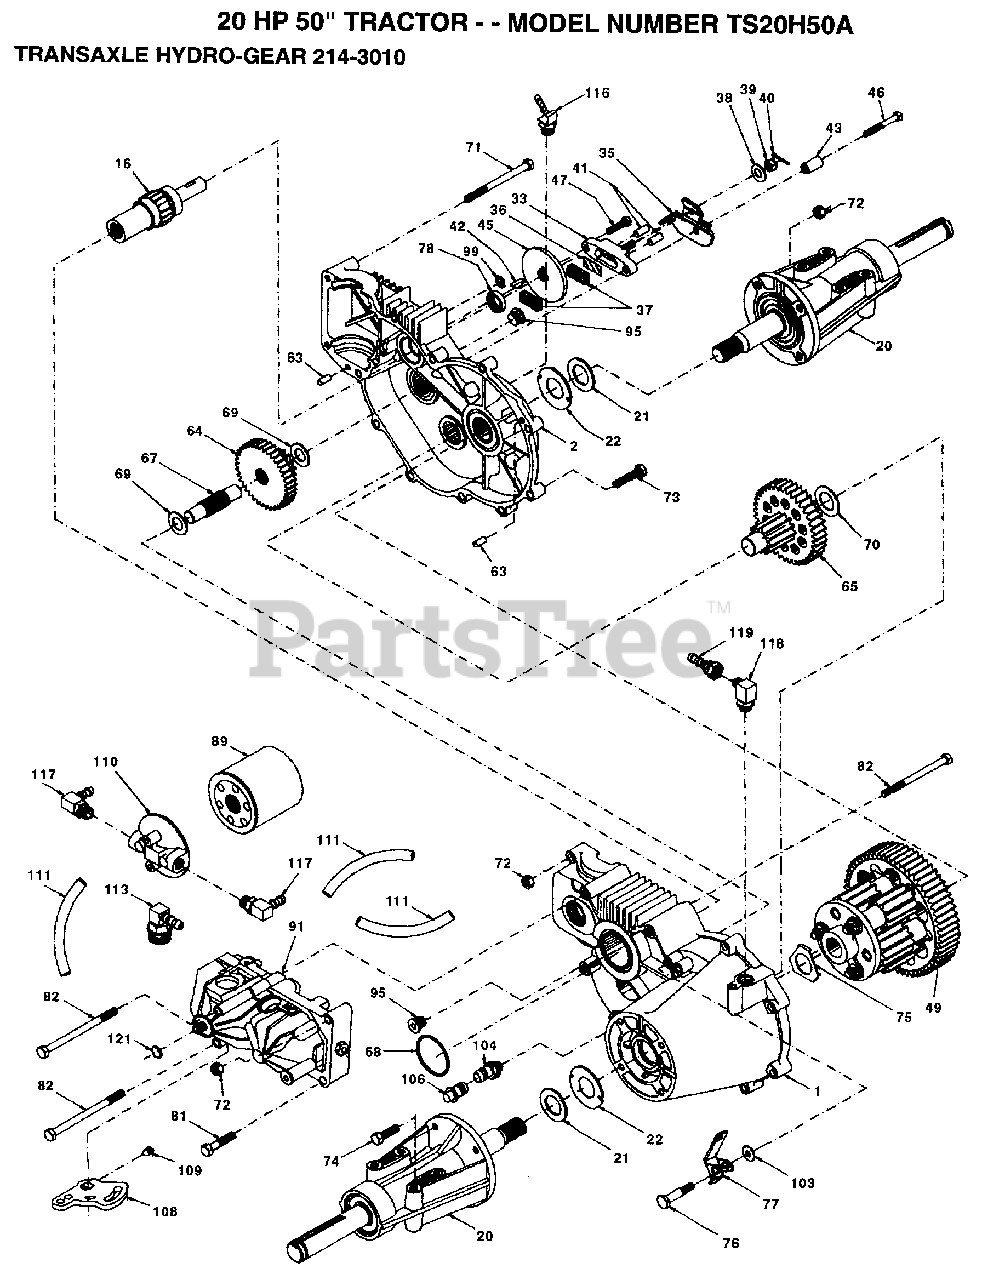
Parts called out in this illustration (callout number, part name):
1	HOUSING LH 70086
2	HOUSING RH 70088
16	SHAFT BRAKE 62877
20	AXLE MTG 70087
21	WASHER 44805
22	WASHER 44806
33	YOKE.BRAKE.62589
35	ARM BRAKE 50214
36	PUCK PLATE 44134
37	PUCK BRAKE 44132
38	WASHER HYD 44130
41	PIN BRAKE 44127
42	KEY HI PRO 44143
43	SPACER 50259
45	DISC BRAKE 44090
46	BOLT 1/4-20 44276
47	BOLT 1/4-20 44433
49	DIFFERENTIAL62834
63	PIN DOWL 44757
64	GEAR R14-38 44775
65	PINION DRIV 70051
67	SHAFT-44779
68	O RING 44781
69	WASHER 44795
70	WASHER 44794
71	BOLT 5/16 44827
72	NUT HXLK 43064
73	BOLT 5/16 44841
74	SCREW 5/16 45089
75	WASHER DIF 44880
76	BOLT SHOULD 44785
77	ARM FREEWHL 44786
78	SEAL.OIL.44761
81	BOLT 5/16 43084
82	BOLT 5/16 44820
89	FILTER SPIN 50037
95	PLUG.9005110-5600
103	WASHER.50169
104	CAP.VENT.70109
106	O-RING.ASM.70110
108	ARM.CONTROL.45007
109	SCREW.SET.50018.
110	FILTER.HEAD.50207
111	HOSE.5/16.50208.
113	FITTING.SAE.50210
116	FITTING.SAE.50213
117	FITTING.SAE.50249
118	FITTING.MAL.50251
119	FITTING.FEM.50250
121	RING.RET.2003016.
